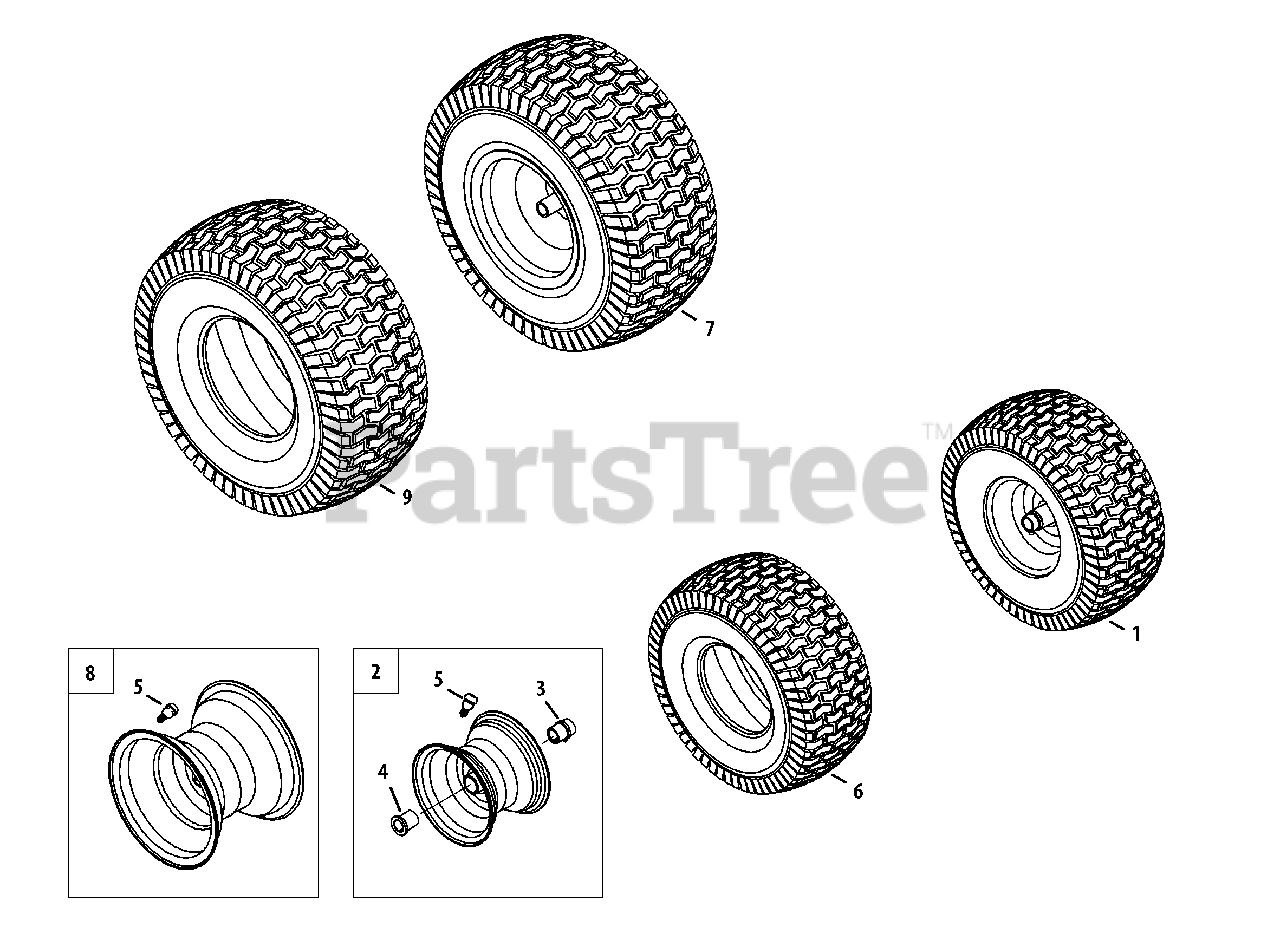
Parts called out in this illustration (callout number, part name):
1	Wheel Ass’y, Complete, 15 x 6 x 6
2	Rim Ass’y, 6.0 x 4.5, Flange Bearings
3	Bearing, Flange, .760 ID w/ Fitting
4	Bearing, Flange, .760 x 1.00 x 1.20
5	Valve, Tubeless Air
6	Tire, 15 x 6 x 6 Sq Shoulder
7	Wheel, Complete, 20 x 8 x 8
8	Rim Ass’y, 8.0 x 7.0 x .750 ID
9	Tire, 20 x 8 x 8 Sq Shoulder
